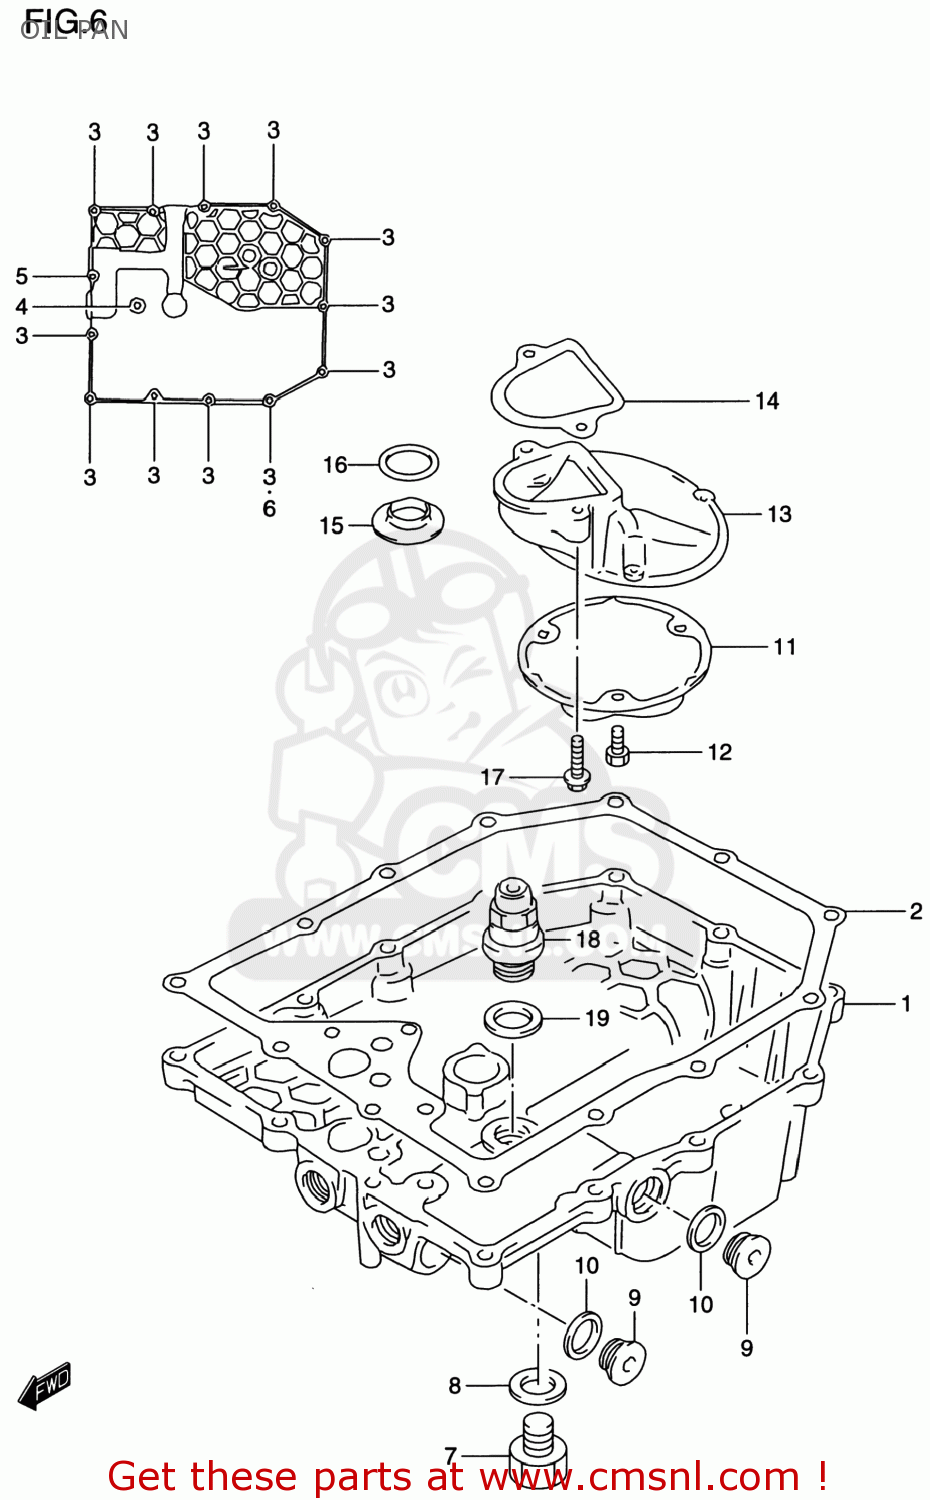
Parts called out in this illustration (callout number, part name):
1	PAN,OIL
2	GASKET,OIL PAN (NAS)
3	BOLT
4	BOLT
5	BOLT
6	GASKET(5.8X11X1.2) (NAS)
7	PLUG
8	GASKET(13.8X18.8X4.8) (NAS)
9	PLUG,16X8
10	GASKET(16X22X2) (NAS)
11	STRAINER,ENGINE OIL
12	BOLT
13	PROTECTOR,OIL STRAINER
14	GASKET,OIL STRAINER PROTECTOR (NAS)
15	GASKET,OIL OUTLET (NAS)
16	O RING(D:3.2,ID:17.8)
17	BOLT
18	VALVE ASSEMBLY,OIL RELIEF
19	GASKET(16X22X2) (NAS)
